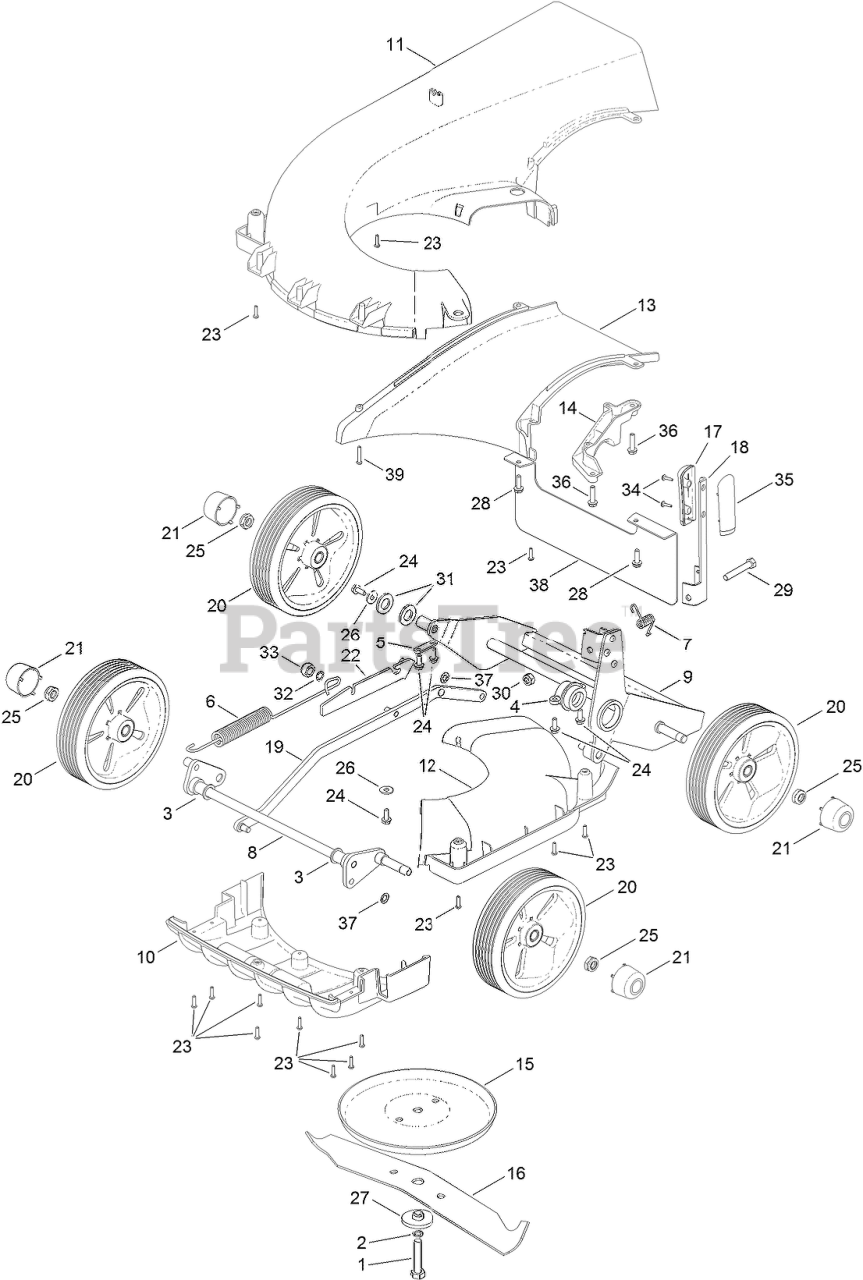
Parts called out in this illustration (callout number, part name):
1	BOLT-UNF
2	WASHER-SPRING
3	BEARING-AXLE, FRONT
4	HOUSING-PIVOT BEARING, LH
5	PLATE-SECURING
6	SPRING-COUNTER BALANCE
7	SPRING-HOC
8	AXLE-FRONT
9	FRAME-WHEEL
10	MOULDING-FIN
11	MOULDING-SNAIL DECK
12	MOULDING-ACCESS, SNAIL DECK
13	MOULDING-THROW PLATE
14	MOUNT-BEARING
15	DISC-FRICTION
16	CUTTERBAR
17	KNOB-HOC, RH
18	LEVER-HOC
19	ROD-CONNECTING BAR
20	WHEEL ASM
21	CAP-WHEEL, CENTER
22	MOUNT-SPRING
24	SCREW M6 X 16 TAPTITE HEX HD
25	NUT-NYLOC
26	WASHER
27	SPACER-DISTANCE, CUTTERBAR
28	SCREW-TAPTITE
29	SCREW-HH
30	NUT-HEX, NI
31	WASHER-PLAIN
32	WASHER-SHAKEPROOF
33	NUT-NYLOC
35	KNOB-HOC, LH
36	SCREW-HH
37	WASHER-STARLOCK
38	GUARD-REAR
